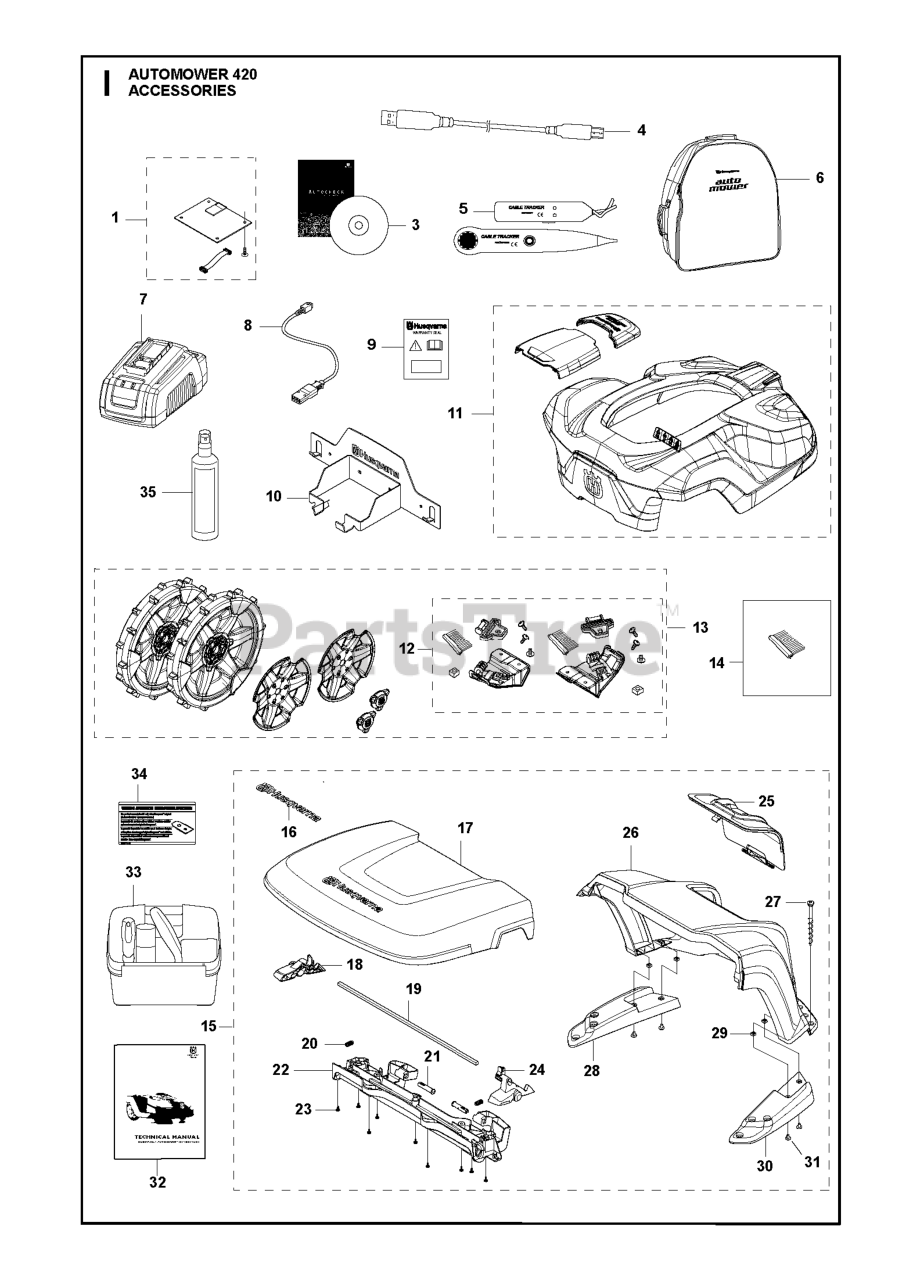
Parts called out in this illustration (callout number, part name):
1	IMPELLER ASSY
2	GEARBOX.ASSEMBLY.AUGER
3	BEARING FLANGE
4	PULLEY, IMPELLER
5	BASE DISCHARGE CHUTE
6	BRACKET, CORNER DISCHARGE
7	CLEAN OUT TOOL
8	CLIP.CLEANOUT.TOOL
9	LOCKNUT.NYLOC.1/4-20
10	SCREW.HEX.HD1/4-20X
11	NUT.FLANGE.5/16
12	BOLT, HEX HEAD 5/16-18
13	WASHER, FLAT
14	WASHER.LOCK.HVY.HLCL.SPR.5/16
15	CAPSCREW.HX.HD.5/16-18X1.00.NY
16	BOLT.CARRIAGE.5/16-18X
17	SCREW.HWH.13-16-5.8.BZP
18	CASE PLUG
19	GEARBOX HOUSING-RH
20	GEARBOX GASKET
21	OIL SEAL
22	FLANGE BUSHING-1"
23	WASHER TRUST 1"
24	WORM GEAR
25	AUGER SHAFT
26	KEY, SQUARE 1/4 X .875
27	FLANGE BUSHING-5/8
28	WASHER, THRUST 5/8
29	SHAFT, IMPELLER
30	PIN, ROLL 3/16 X 1-1/8
31	WASHER, THRUST 3/4
32	BEARING TRUST 3/4 NTA-1220
33	BUSHING, FLANGE 3/4
35	HEX SCREW-5/16 X 3/4
36	HOUSING.GEARBOX.LH(SERVICE)
